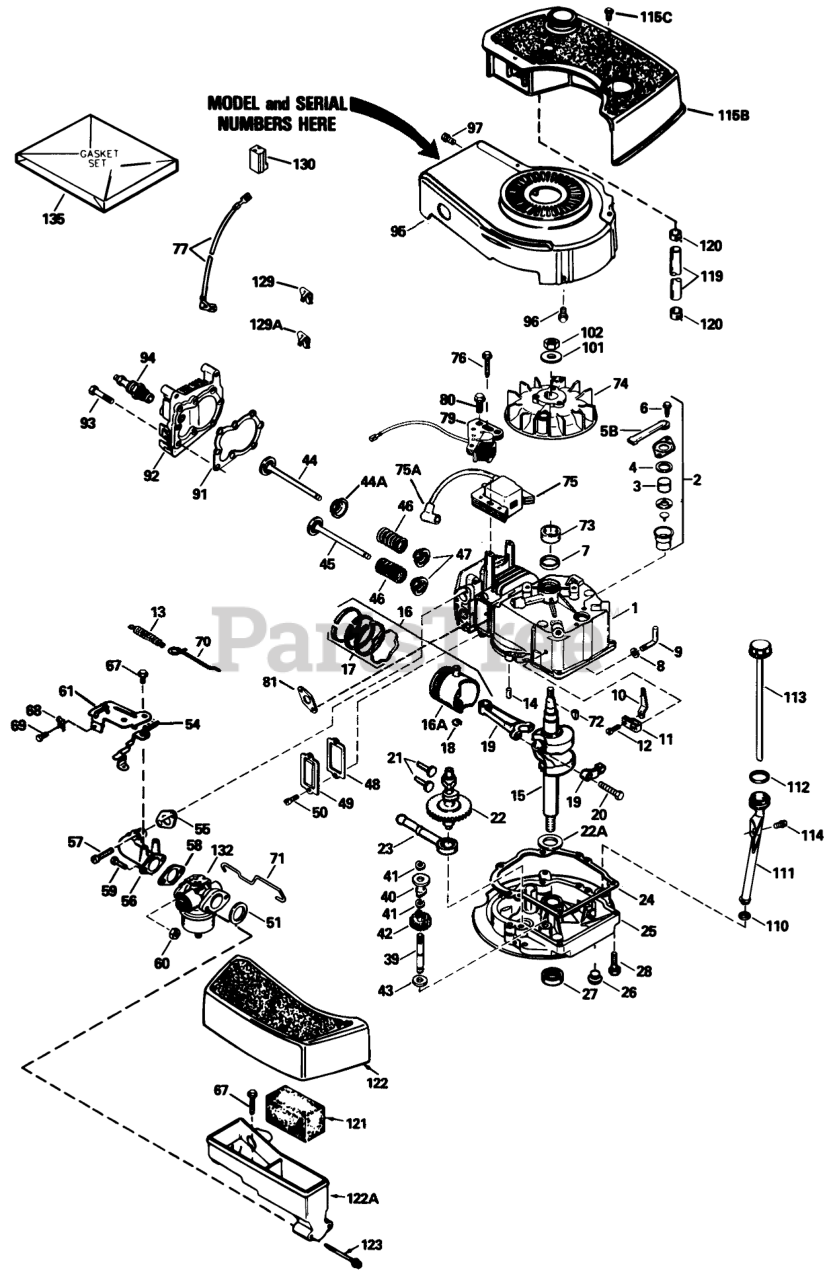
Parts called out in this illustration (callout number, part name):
1	Cylinder Assy. (Incl. Ref. #6 & 14)
2	Breather Assy. (Incl. Ref. #3-6 & 129)
3	Element-Breather
4	33735 Gasket, Breather
5B	Tube, Breaker
6	Screw (10-24 x 9/16)
7	Seal-Oil
8	Washer-Flat
9	Rod, Governor (Incl. Ref. #8)
10	Governor Lever
11	Clamp-Lever, Governor
12	Screw
13	Spring Governor
14	Pin-Dowel
15	Crankshaft
16	Piston, Pin & Ring Assy. (STD.)(Incl. Ref. #16A, 17 & 18)
16	Piston, Pin & Ring Assy. (.010 oversize)(Incl. Ref. #16A, 17 & 18)
16	Piston, Pin & Ring Assy. (.020 oversize)(Incl. Ref. #16A, 17 & 18)
16A	Piston & Pin Assy. (Std.)(Incl. Ref. #18)
16A	Piston & Pin Assy. (.010 oversize)(Incl. Ref. #18)
16A	Piston & Pin Assy. (.020 oversize)(Incl. Ref. #18)
17	Ring Set-Piston (Std.)
17	Ring Set, Piston(.0100versize)
17	Ring Set (.020" OS)
18	Ring-Retaining, Piston Pin
19	Rod Assy., Connecting (Incl. Ref. #20)
20	Bolt-Rod, Connecting
21	Lifter-Valve
22	Camshaft(Mech.Comp. Release)
22A	Washer-Thrust
23	Oil Pump ASM
24	Gasket
25	Flange, Mounting (Incl. Ref. #26, 27 & 39)
26	Plug Oil Drain
27	Seal-Oil
28	Screw (1/4-20 x 1-1/4)
39	Shaft-Governor
40	Spool-Governor
41	Ring-Retaining
42	Gear Assy., Governor (Incl. Ref. #43)
43	Washer
44	Valve, Intake (Std.)(Incl. Ref. #47)
44	Valve, Intake (1/32" oversize)(Incl. Ref. #47)
44A	Seal Assy., Intake
45	Valve, Exhaust (Std.)(Incl. Ref. #47)
45	Valve, Exhaust (1 /32" oversize)(Incl. Ref. #47)
46	Spring-Valve
47	Cap-Valve, Spring
48	Gasket-Cover, Valve
49	Cover-Valve
51	Gasket-Air Cleaner
54	Lever Control
55	Gasket-Intake Pipe
56	Pipe, Intake (Incl. Ref. #55)
57	Screw (1/4-20 x 1)
58	Gasket-Carburetor
59	Screw (1/4-28 x 7/8)
60	Nut and Lock Washer (1/4-28)
61	Bracket Assy., Control (Incl. Ref. #54 & 67)
67	Screw, Hex Washer Hd Shoulder Self-Tap
68	Conduit
69	Screw (10-32 x 3/8)
70	Link Governor Spring
71	Link-Throttle
72	Key-Flywheel
74	Flywheel
75	Solid State
75A	Cover-Spark Plug
76	Screw
77	Wire-Ground
79	Coil, Alternator
80	Screw (8-32x27/64)
81	Gasket, Exhaust
91	Gasket-Cylinder Head
92	Head-Cylinder
93	Screw (5/16-18x1-1/2)
94	Spark Plug-Resistor (R J19 L M)
95	Housing-Blower
96	Screw (1/4-20x19/32)
97	Screw (10-24 x 9/16)
101	Washer-Belleville
102	Nut-Flywheel
111	Tube, Oil Fill
113	Dipstick, Oil
114	Screw (10-32 x 1/2)
115B	Tank Assy. (Incl. Ref. #118 & 120)
115C	Screw (10-32 x 35/64)
119	Line-Fuel
120	Clamp-Line, Fuel
121	Filer, Air
122	Cove, Air Cleaner
122A	Body Air Cleaner
123	Screw Fil Hd.
129	Clip-Wire
129A	Clip, Breather
130	Connector-Body
132	Carburetor (Incl. Ref. #58)
135	Gasket Set
